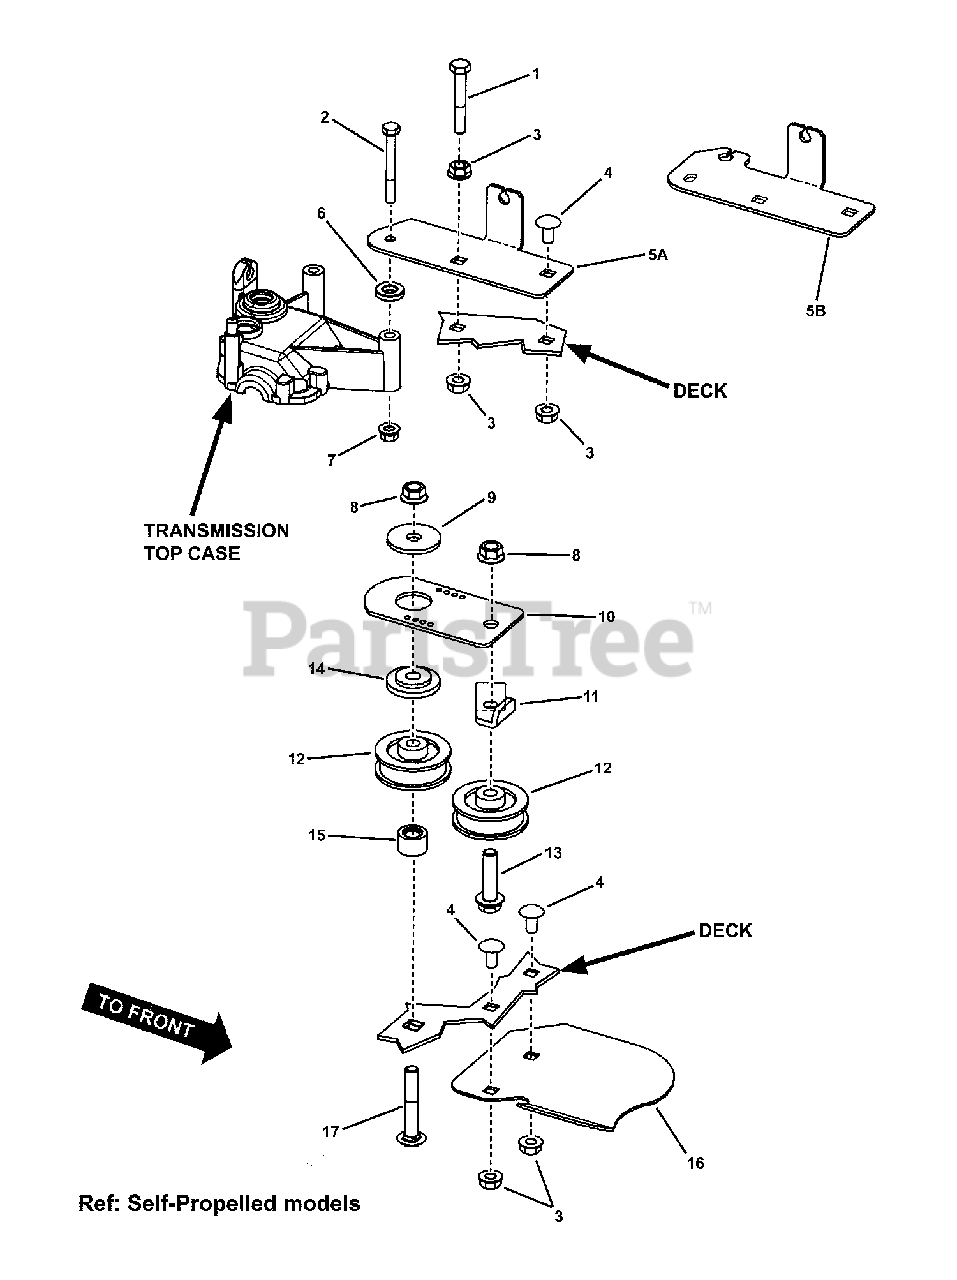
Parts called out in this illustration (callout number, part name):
1	SCREW, 5/16-18 x 2" Hex Head Cap, GR 5
2	SCREW, 1/4-20 x 2-1/4" Hex Head Cap, GR 5
3	NUT, 5/16-18 Hex Flange Lock
4	BOLT, 5/16-18 x 5/8" Round Head Short Square Neck Carriage
5A	BRACKET, Transmission Mounting
5B	BRACKET, Transmission Mounting
6	SPACER, 3/8 x 13/16 x 5/32
7	NUT, 1/4-20 Hex Top Lock Flange
8	NUT, 3/8-16 Hex Flange Lock
9	WASHER, 13/32 x 1-1/2 x 1/8" Flat
10	IDLER ARM, Belt Drive
11	BELT GUIDE, Idler
12	PULLEY, Flat Idler, Plastic
13	BOLT, 3/8-16 X 1-1/2" Hex Flange Lock, GR 5
14	SPACER, Pivot, Belt Idler
15	SPACER, Idler
16	SHIELD, Debris
17	BOLT, 3/8-16 x 2-1/4" Short Square Neck Carriage, GR 5
